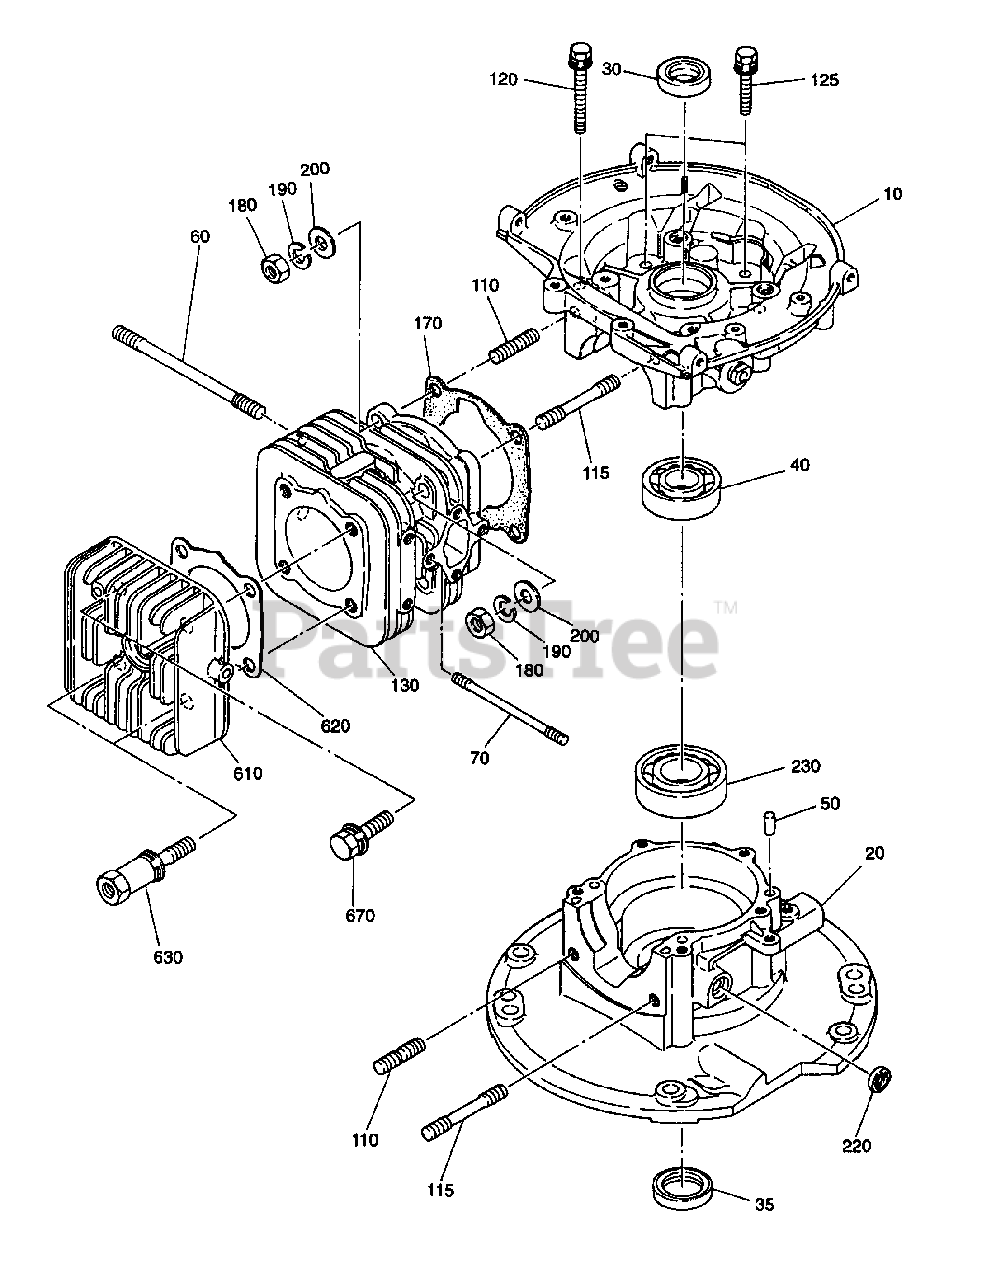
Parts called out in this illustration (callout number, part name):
10	CRANK CASE (Complete, includes items 20, 30, 35, 40, 50, 110, 115, 120, 125, & 230)
30	OIL SEAL
35	OIL SEAL
40	BALL BEARING
120	BOLT AND WASHER ASSY
125	BOLT AND WASHER ASSY
130	CYLINDER CP
170	GASKET (CYLINDER)
190	SPRING WASHER
220	OIL SEAL
230	BALL BEARING
610	CYLINDER HEAD
620	GASKET CP (HEAD)
630	BOLT AND WASHER ASSY
670	BOLT AND WASHER ASSY
